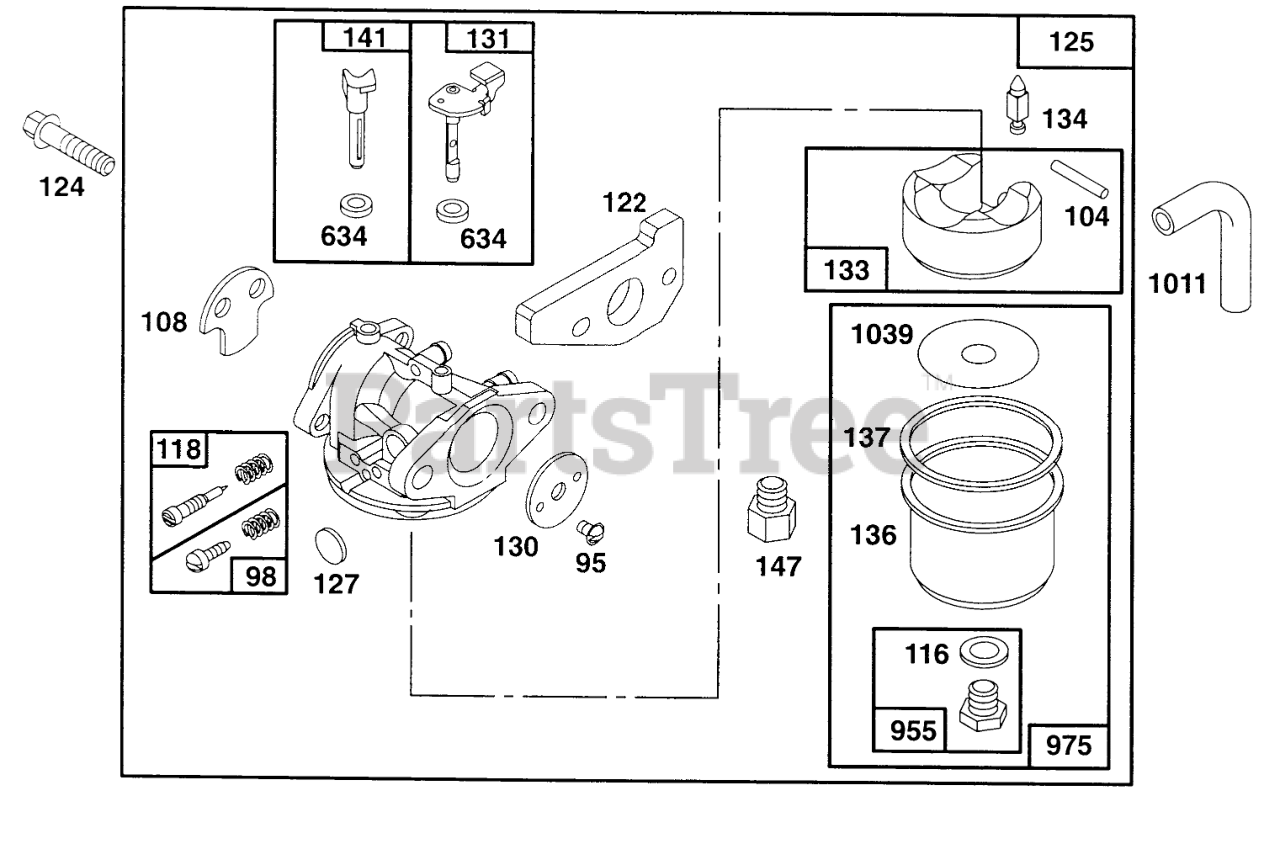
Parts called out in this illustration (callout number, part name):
95	SCREW - ROUND HEAD
98	IDLE ADJUSTING SCREW
104	FLOAT HINGE PIN
108	CHOKE VALVE
116	SEALING GASKET
118	VALVE KIT - NEEDLE
122	ADAPTER ASSEMBLY
124	HEX HEAD SCREW
125	CARBURETOR ASSEMBLY
127	PLUG
130	THROTTLE VALVE
131	THROTTLE SHAFT
133	FLOAT-CARBURETOR
134	Valve-Inlet(Includes Seat)
136	FLOAT BOWL
137	FLOAT BOWL GASKET
141	CHOKE SHAFT
147	JET ADAPTER
634	SEAL WASHER
955	HEX HEAD SCREW
975	CARBURETOR BOWL ASM
1011	VENT TUBE
1039	FLOAT LIMITER
